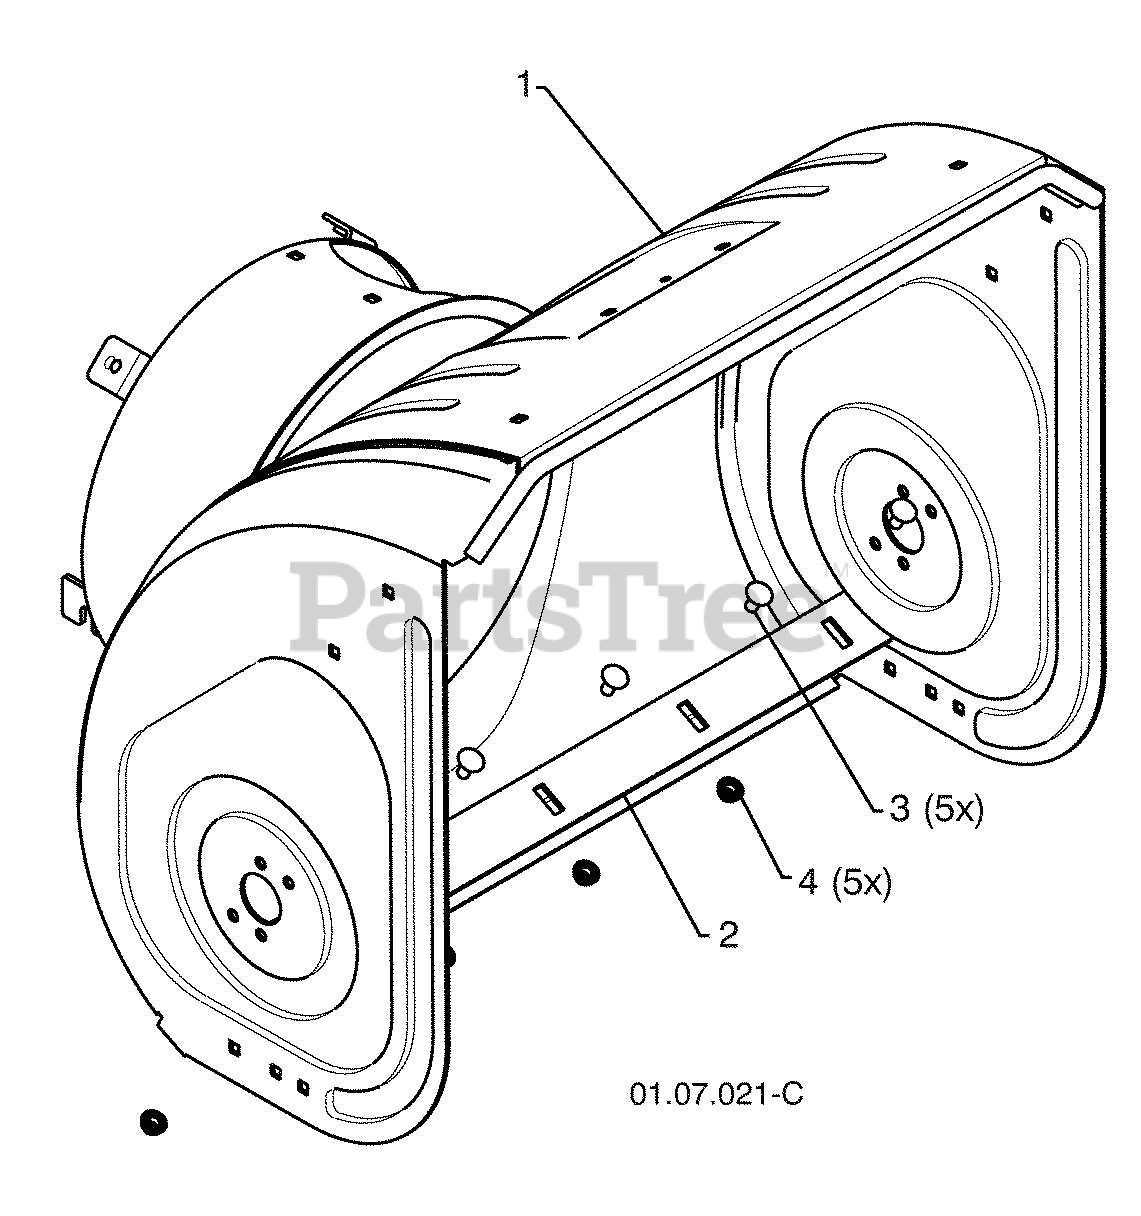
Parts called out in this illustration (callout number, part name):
1	AUGER HOUSING
2	SCRAPER BAR
3	CARRIAGE BOLT 5/16-18 X .625
4	NUT 5/16-18
